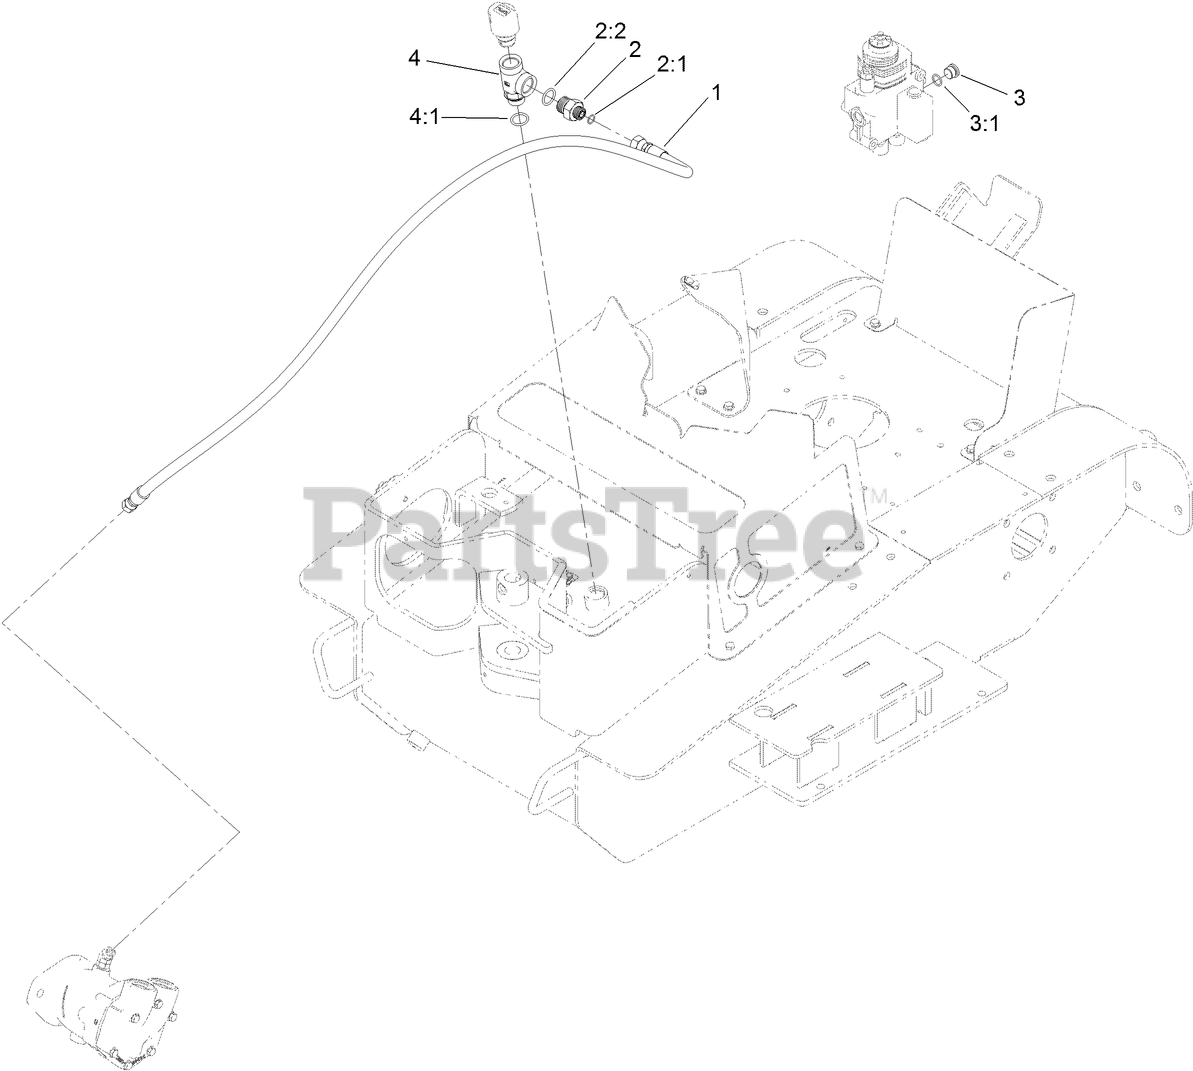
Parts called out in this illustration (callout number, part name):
1	HOSE-HYD
2	FITTING-STR
2:1	O-RING
2:2	O-RING
3	PLUG-HEX
3:1	O-RING
4	FITTING-TEE
4:1	O-RING
